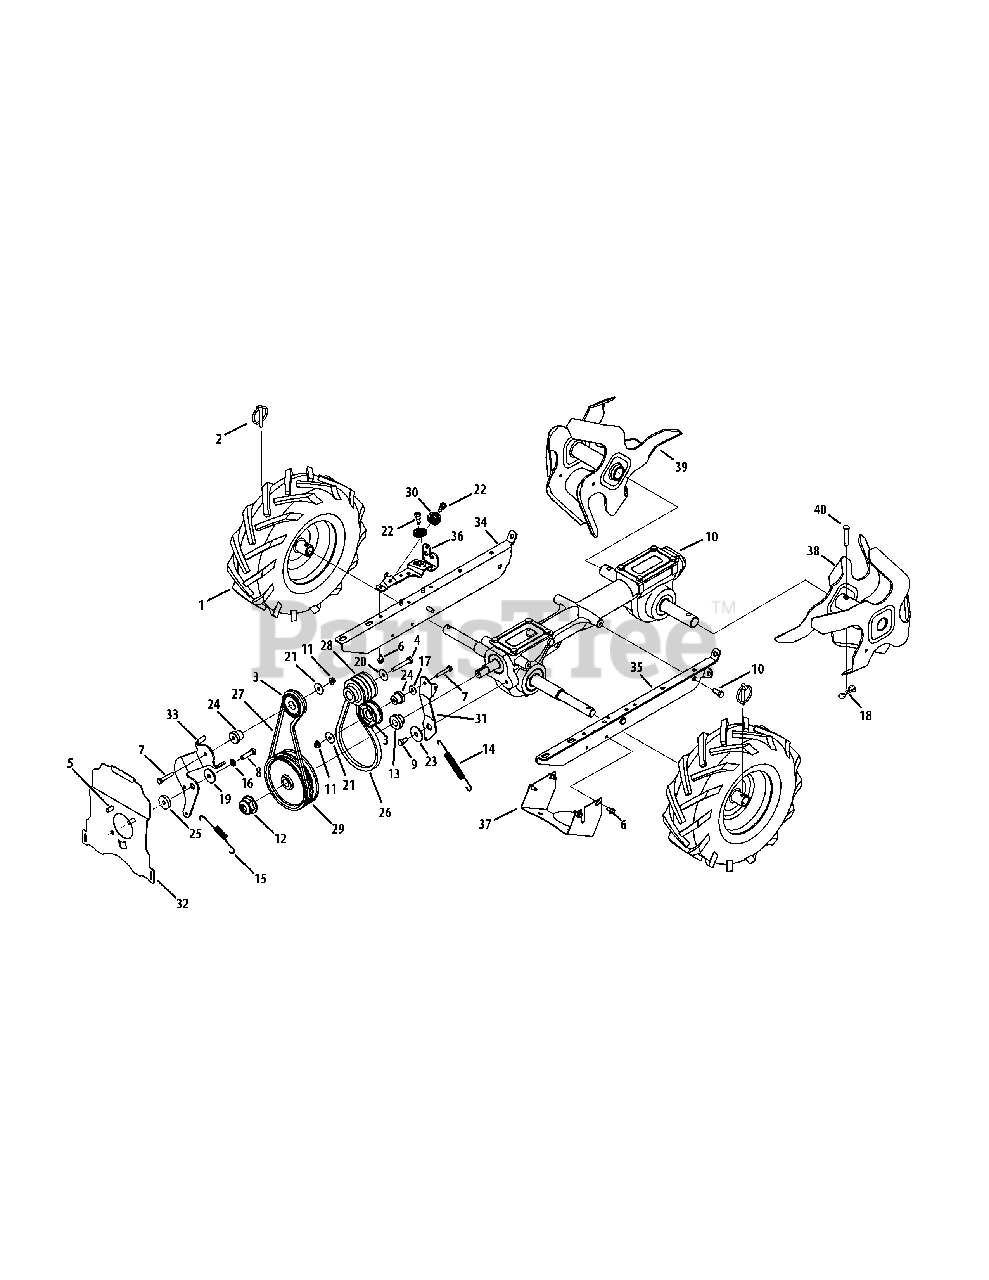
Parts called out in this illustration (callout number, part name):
1	Complete Wheel Assembly, 13 x 5 x 6 (B, C)
2	Click Pin
3	Idler Pulley Assembly
4	Hex Screw, 3/8-24 x 2.00
5	Hex Screw, 5/16-24 x .625
6	Self Tapping Screw, 1/4-20 x .500
7	Hex Screw, 1/4-20 x 1.50
8	Hex Screw, 5/16-18 x 1.25
9	Hex Screw, 5/16-18 x .75, Patch
10	Transmission Assembly
11	Hex Lock Nut, 1/4-20
12	Nut, 9/16-18, Flange Lock
13	Hub, 5/8 Spline
14	Extension Spring, .480 OD X 5.00 LG
15	Extension Spring, LT5 PTO
16	Lock Washer, 5/16
17	Washer, .28 x .74 x .063
18	Internal Cotter Pin
19	Flat Washer, .330 X 1.25 X .120
20	Bell Washer, .396 x 1.140 x .095
21	Flat Washer, .265 x 1.0 x .030
22	Shoulder Screw, .342 x .335 1/4-28
23	Pivot Idler Spacer
24	Shoulder Spacer, .260 x .785 x .538
25	Pivot Idler Spacer
26	V-Belt, 4L x 25.375 Long
27	V-Belt, 3L x 29.125 Long
28	Engine Pulley
29	Transmission Pulley
30	Cable Roller
31	Idler Bracket, Forward
32	Cover Plate
33	Idler Bracket, Reverse
34	Mounting Frame, RH
35	Mounting Frame, LH
36	Pulley Bracket
37	Pulley Shield
38	Tine Assembly, LH
39	Tine Assembly, RH
40	Clevis Pin, .375 x 1.75
